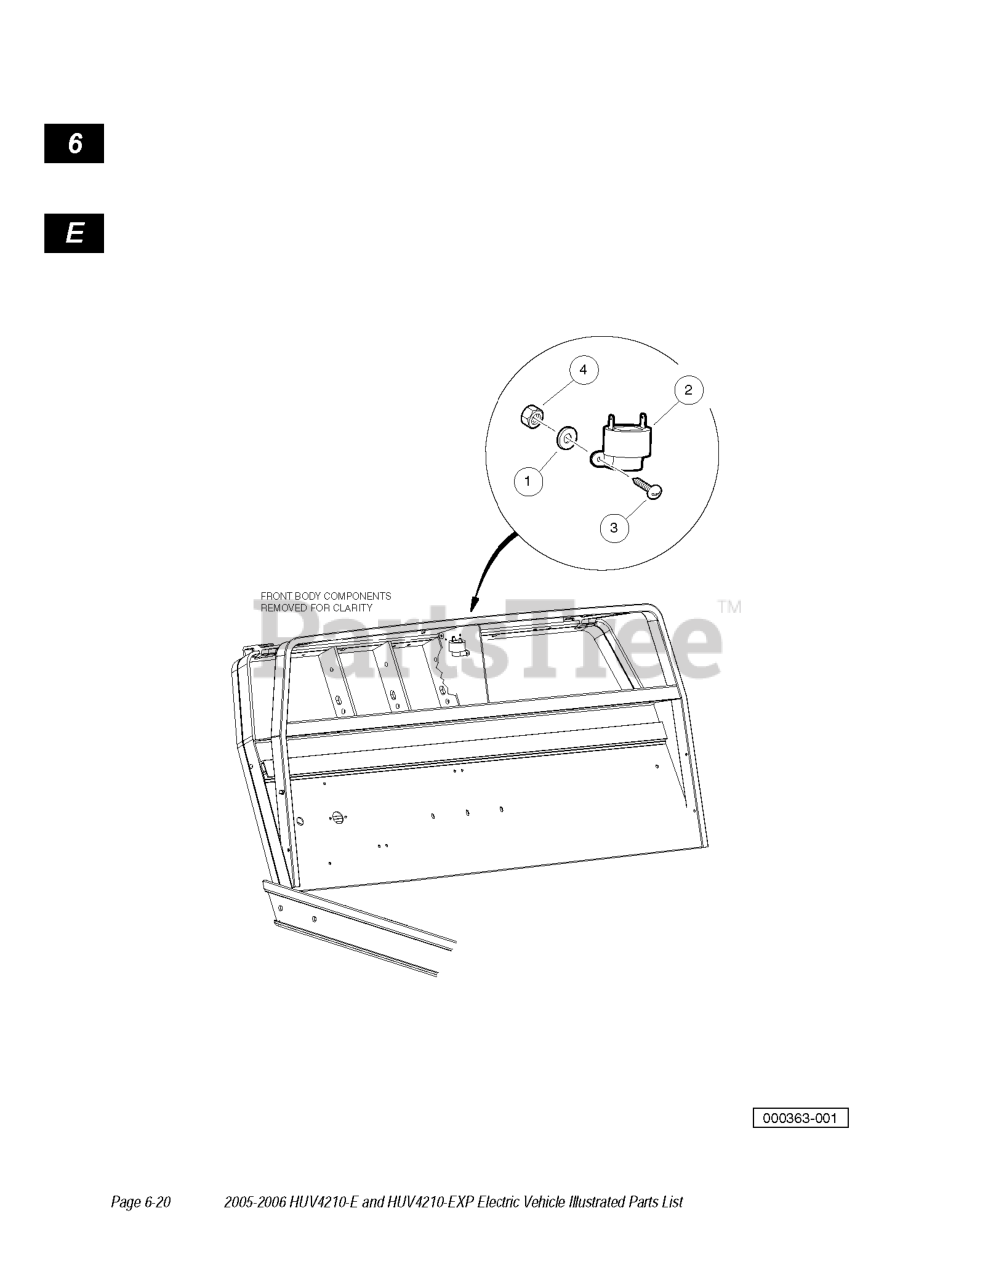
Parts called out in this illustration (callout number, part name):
2	BUZZER, 9-48 VDC REVERSE
3	SCREW, #4-40 X .75 RD HD MACH
4	NUT HEX MACHINE
